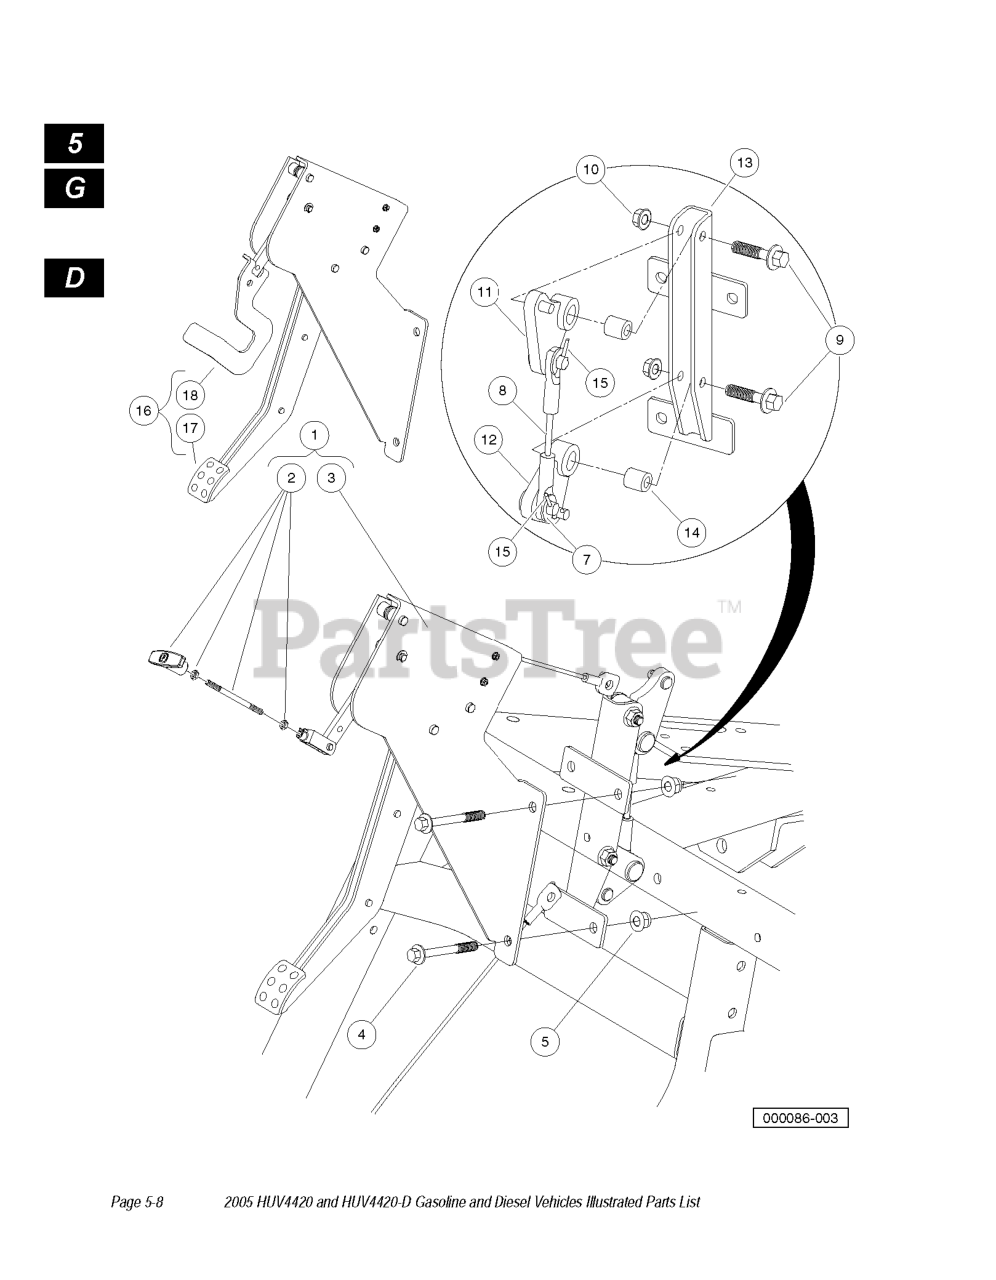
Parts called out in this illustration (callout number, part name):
2	KIT-HANDLE-BRAKE-PARK
4	BOLT FLG, M8X1.25X65
5	LOCK NUT, FLG M8 X 1.25 NYLON
7	WASHER, FLAT, 3/8, BLK FIN
8	CABLE, CRANK BELL
12	ASM, BELLCRANK, LOWER
13	BRKT, BELLCRANK, PRK BRK, AWD
14	SPACER, PIVOT, PARK BRK, AWD
15	PIN,CUT COTTER
16	ASM, PEDAL, BRAKE, HARD
18	HANDLE, RELEASE, PARK BRAKE
